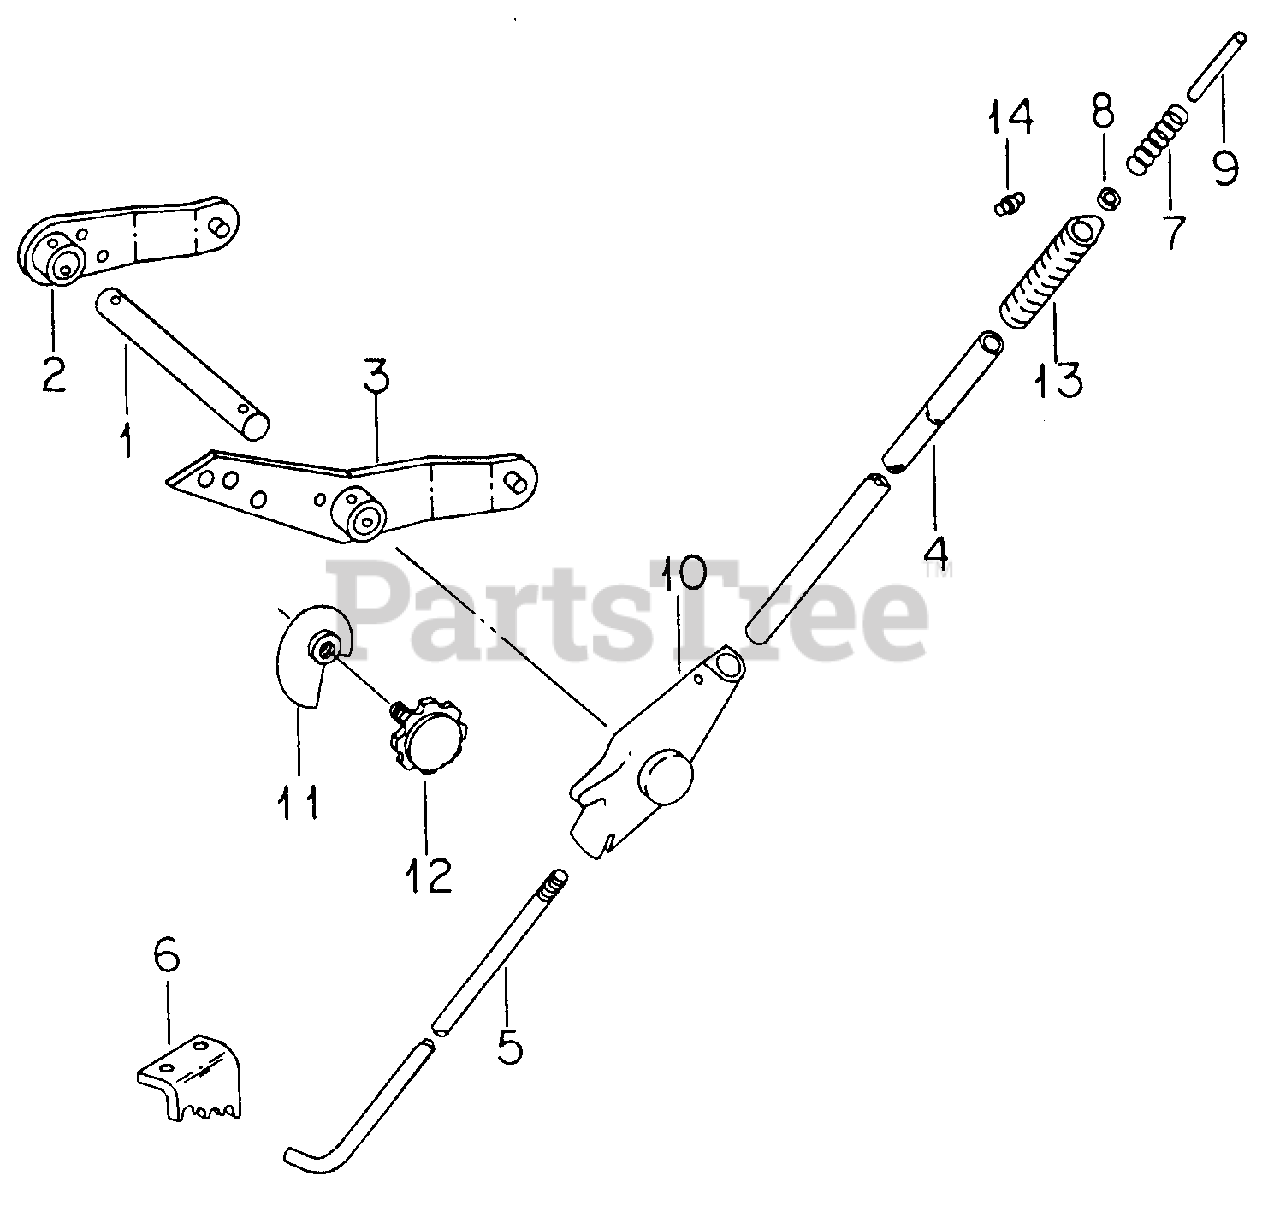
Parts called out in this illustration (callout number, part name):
2	Arm Assy, Lift LH
3	Arm Assy, Lift RH
4	Handle, Lift
5	Rod Assy, Handle Release
6	Ratchet, Lift Handle
7	Spring, Rod Return
8	Retainer, Spring
9	Pin, Release Rod
10	Hub, Lift Handle
11	Cam Assy, Lift Handle Stop
12	Knob, Torque
14	Lock Assy, Release Rod
